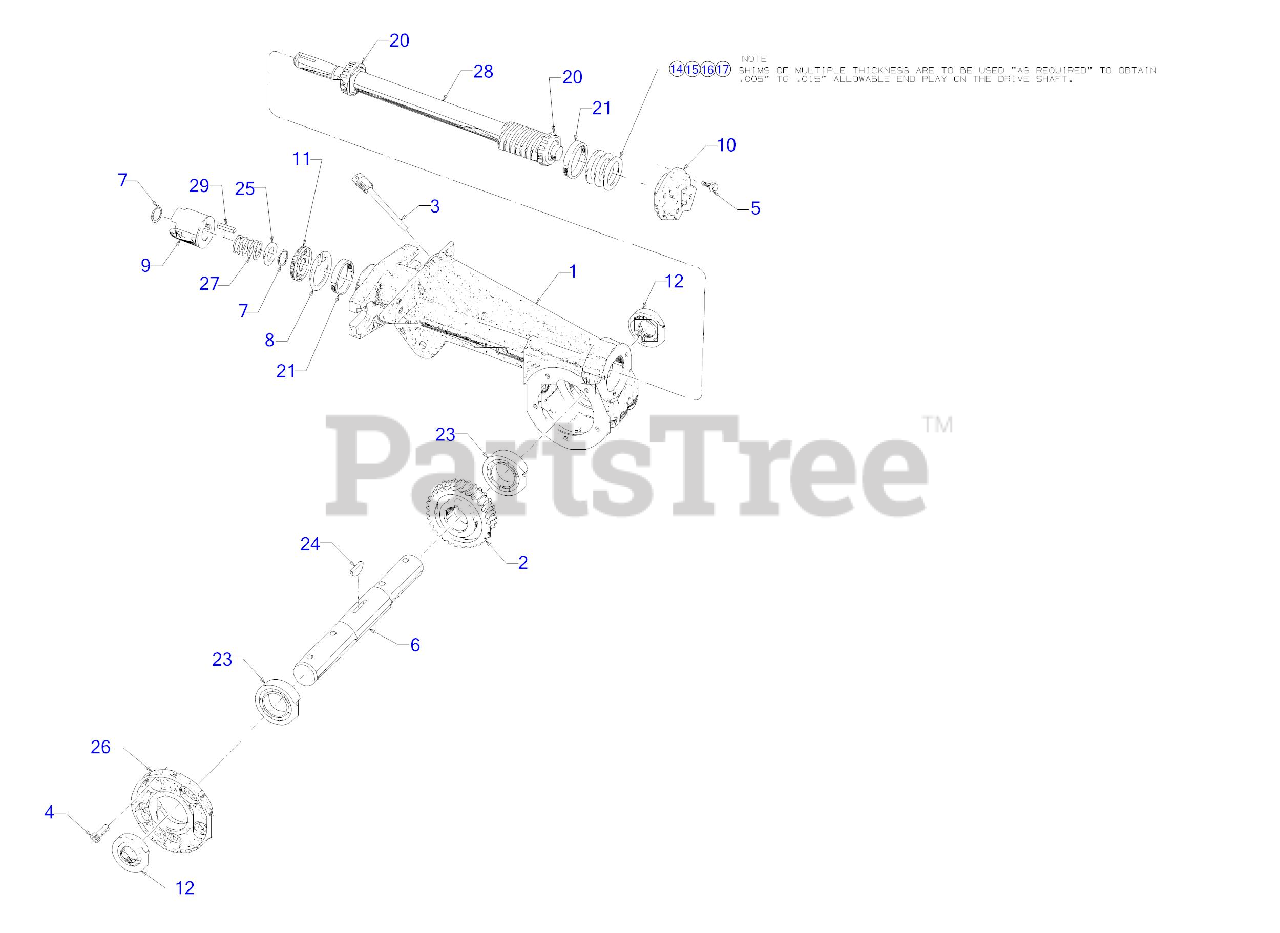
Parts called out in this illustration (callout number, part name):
2	WORM GEAR
3	ASSEMBLY-DIPSTICK HORSE
4	SCREW-SELF SEALING
5	SCREW-HFLK 1/4-20X.8
6	TILLER TINE SHAFT
7	SNAP RING
8	RETAINING RING
9	PTO REAR ATTACH CLUTCH
10	REAR BEARING COVER
11	OIL SEAL .750 SHF x 1.783
12	OIL SEAL .980 SHF x 1.750
14	FLAT WASHER 1.500X1.750X.062
15	FLAT WASHER 1.500X1.750X.005
16	FLAT WASHER 1.500X1.750X.030
17	FLAT WASHER 1.500X1.750X0.010
20	BEARING CONE
21	BEARING CUP
23	PTO SHAFT BALL BEARING
24	WOODRUFF KEY .25 x 1.12"
25	SHIM 1.0X.7656X
26	COVER-TILLER HOUSING
27	COMPRESSION SPRING .766 ID x 1.50 TILR
28	SHAFT KIT-TINE D
29	KEY .188 x 1.0
